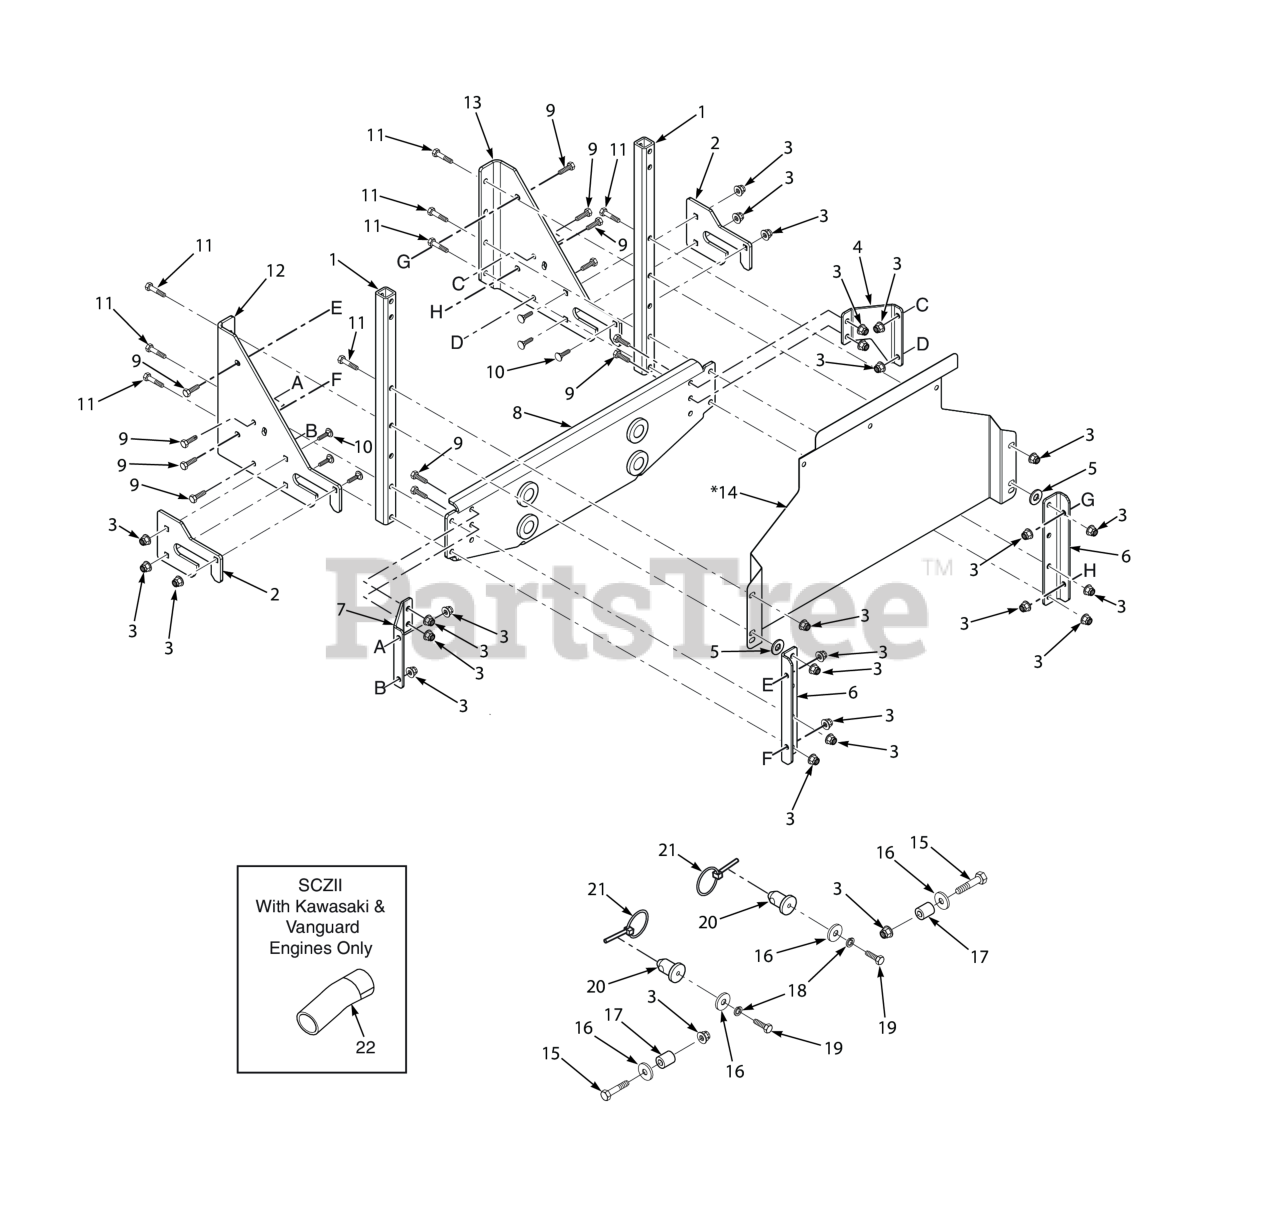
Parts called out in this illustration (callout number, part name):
1	Tube, Upright
2	Wear Plate, GC
3	Nut, Flange Elastic Stop Nut, 3/8-16
4	Angle Brace, LH GC
5	Flatwasher, 7/16-.469 x 1.75 x .25 (48, 52)
6	Mounting Bracket, GC Tube
7	Angle Brace, RH GC
8	Mounting Bracket Weldment
9	Bolt, Hex Head 3/8-16 x 1"
10	Carriage Bolt, 3/8-16 x 1.0"
11	Capscrew, Hex Head 3/8-16 x 2-1/2"
12	RH Mounting Bracket, GC
13	LH Mounting Bracket, GC
14	Heatshield (used on STT & STTII Models Only)
15	Bolt, Hex Head 3/8-16 x 2-1/4" - 61"
16	Flatwasher, 3/8-.406 x 1-1-1/2 x 7 Gauge
17	Spacer
18	Lockwasher, 3/8" Spring, Kawasaki FX / FT & FT-EFI / B&S 32BV
19	Bolt, Hex Head 3/8-16 x 1-1/4" Grade 8
20	Pin, GC Locator
21	Quick Pin, 5/16" Dia.
22	Pipe, Muffler Extension - FX921
